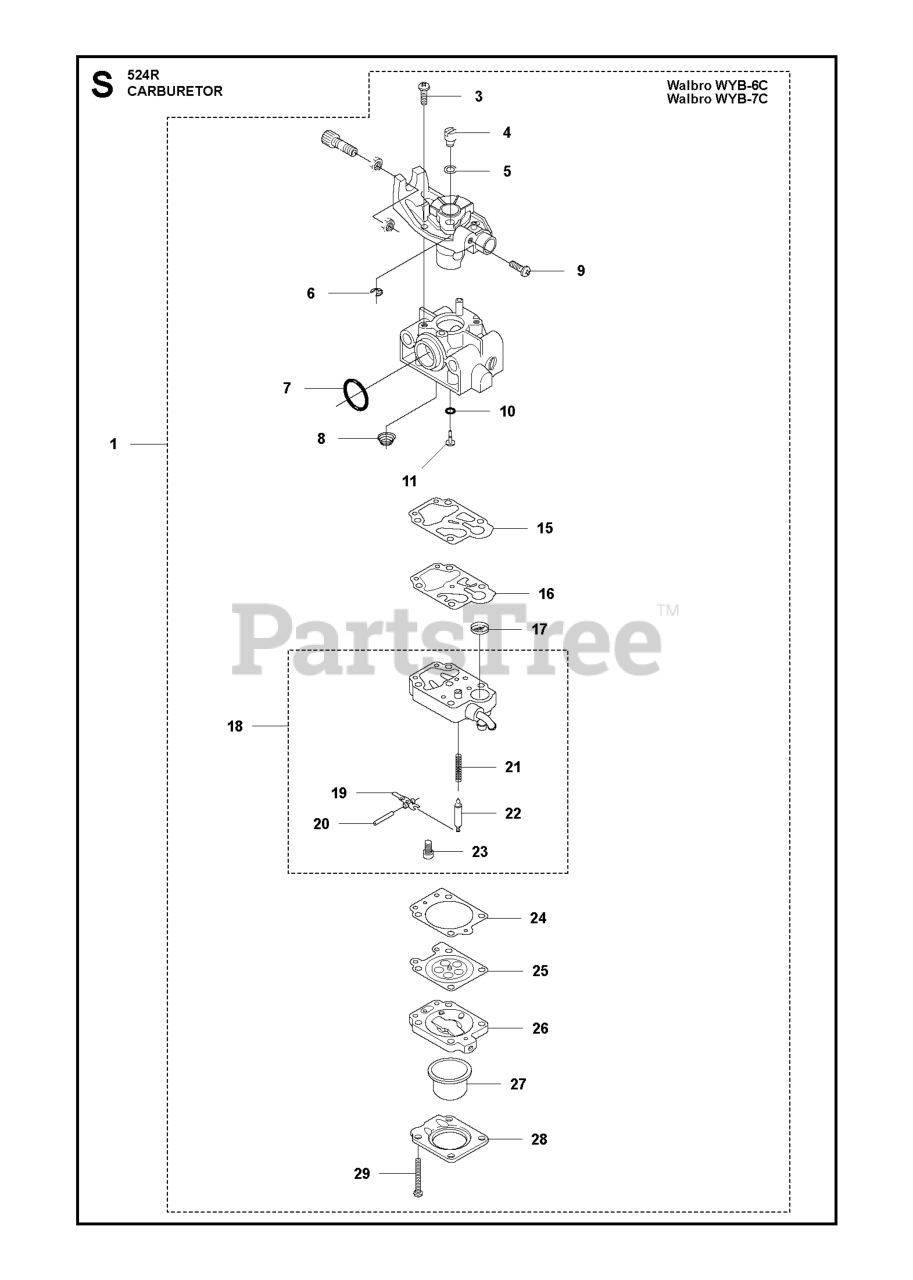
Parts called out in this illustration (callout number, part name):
1	CARBURETOR
1	CARBURETTOR WALBRO WYB7C
6	RETAINING RING
11	JET
16	PUMP DIAPHRAGM
